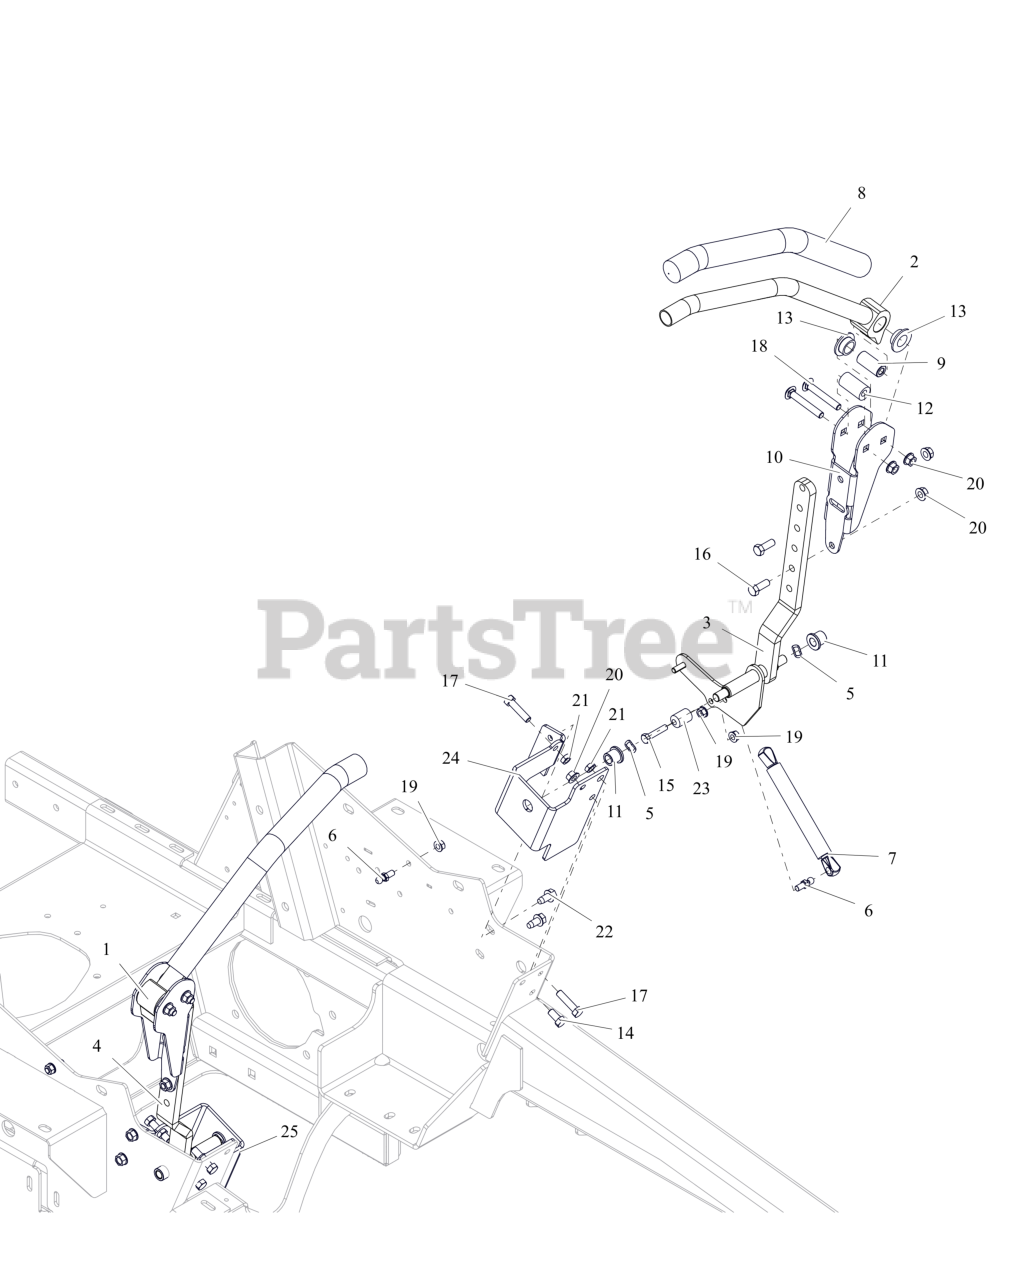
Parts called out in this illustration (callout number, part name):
1	WLDMT, CONTROL HANDLE-LH (RED)
2	WLDMT, CONTROL HANDLE-RH (RED)
3	WLDMT, LH LOWER CONTROL ARM (RED)
4	WLDMT, RH LOWER CONTROL ARM (RED)
5	WAVE WASHER .531X.781X.125FH
6	STUD- BALL
7	DAMPER
8	GRIP, HANDLEBAR
9	SPACER, STEERING ARM
10	BRKT, ADJ UPPER CONTROL ARM (RED)
11	BHSG-FLG .500X.750X.750X.125
12	BSHG, ECCENTRIC.406X.875X1.625
13	BSHG-FLG .762X1.48X.44 NYL
14	BLT,HEX .38-16X.75 G5 ZCC
15	BLT, HEX .31-18X1.50 G5 ZCC
16	BLT,HEX .38-16X1.00 G5 ZCC
17	BLT, HEX 0.375-16X1.5FULL G5 ZCC
18	BLT, RHSSN.38-16X2.50 G5 ZCC
19	NUT,LK-CTR-FLG .31-18 GF ZCC
20	NUT-LK-CTR-FLG .375-16 GF ZCC
21	NUT-JAM .375-16 G2 ZCC
22	SCR,TAP .375-16X.75 HWH TR ZCC
23	ECCENTRIC
24	BRKT, CONTROL ARM - LEFT (RED)
25	BRKT, CONTROL ARM - RIGHT (RED)
